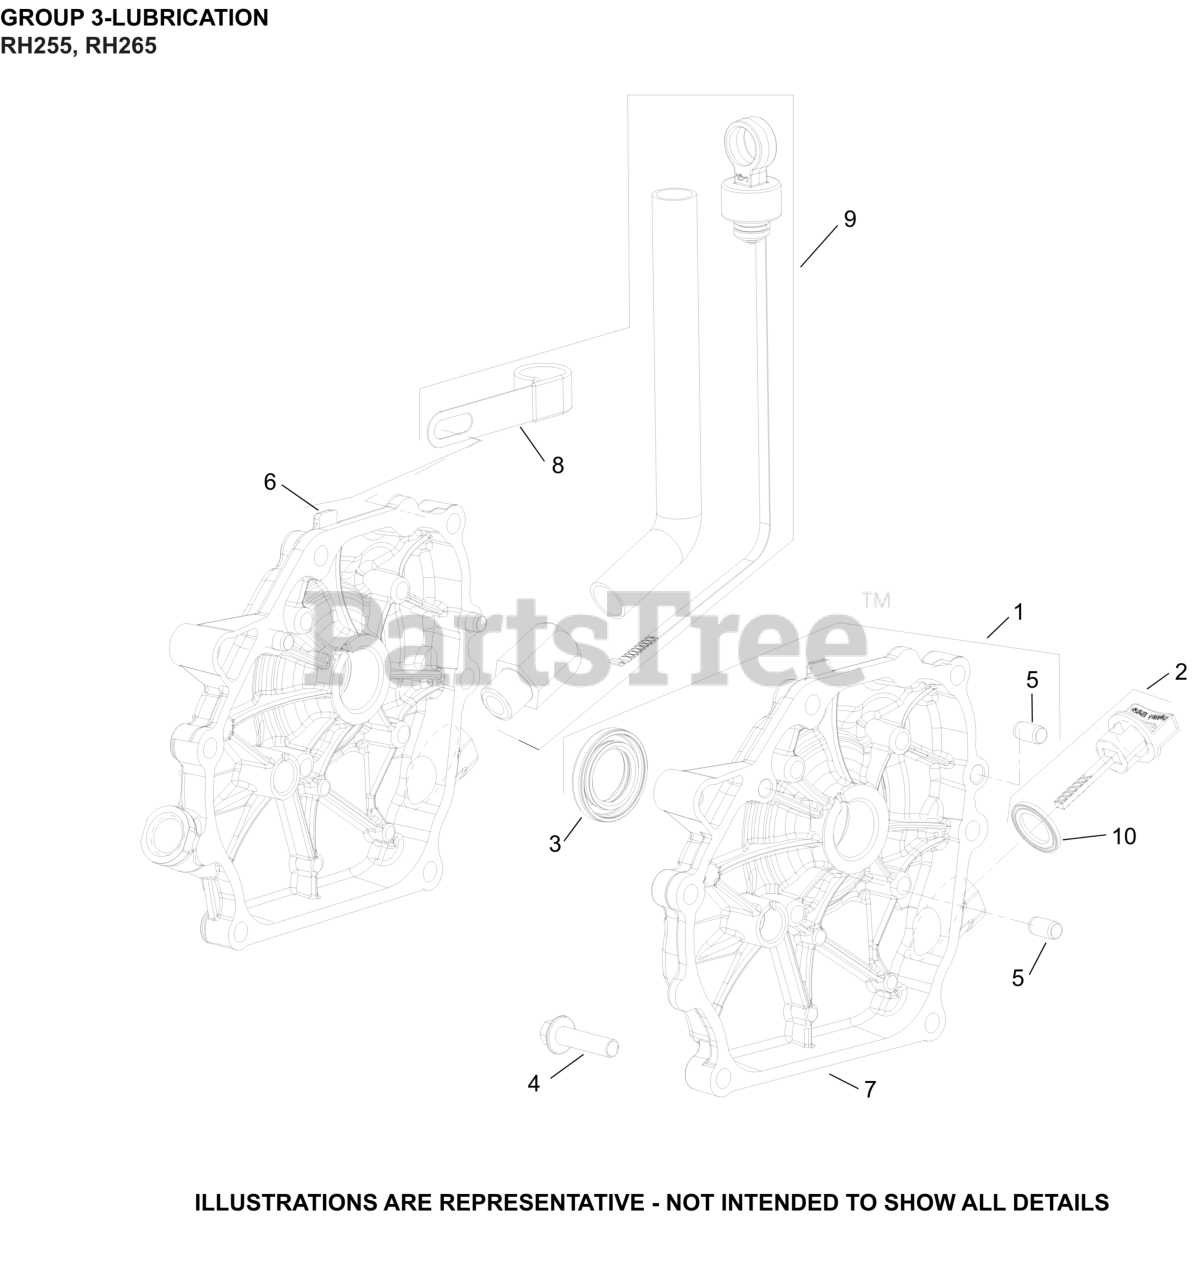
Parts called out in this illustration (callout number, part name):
1	PLATE, CLOSURE ASSEMBLY
2	DIPSTICK ASSEMBLY
3	SEAL - USE 17 032 29-S
4	SCREW, CLOSURE PLATE
5	PIN, DOWEL (8mm)
10	SEAL, DIPSTICK
